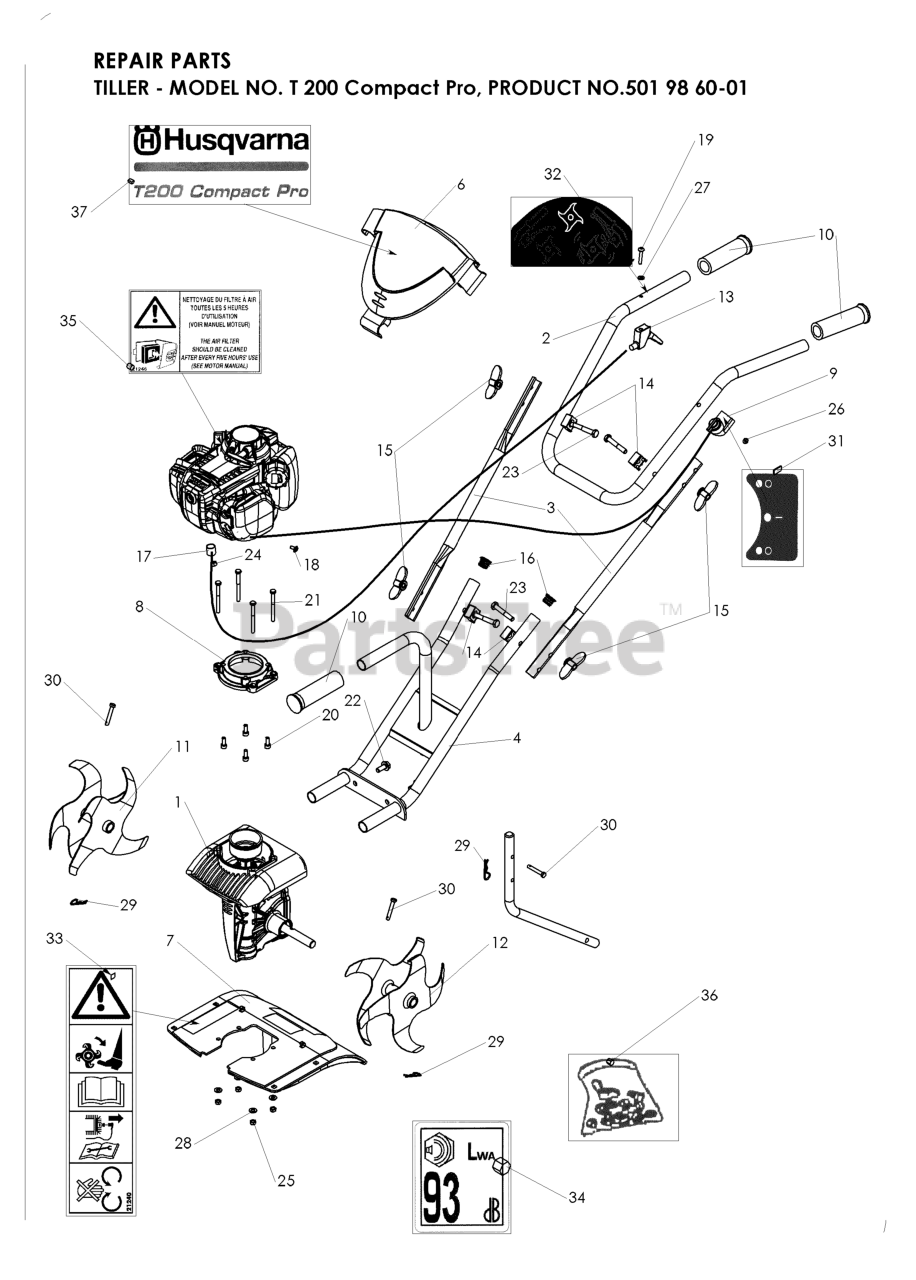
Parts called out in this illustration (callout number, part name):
1	STEERING WHEEL
2	AXLE ASSY
3	SPINDLE.ASM.LH.15"TIRES
4	SPINDLE.ASM.RH.15"TIRES
5	THRUST WASHER
9	BRNG T
10	DRAGLINK.15".TIRES
11	WASHER, LOCK 3/8
13	TUBE, PIVOT AXLE
15	NUT
17	SHAFT ASM STEERING
18	THRUST WASHER
19	STEERING SHAFT SUPPORT
22	SCREW.HX.WSH.HD
23	SHAFT ASSY PITTMAN
25	BRACKET STEERING
26	BUSHING.DRAGLINK (2 2)
27	GEAR.SECTOR
28	WASHER
29	SCREW 3/8-16X3/4
30	COTTER PIN
32	TIE ROD
36	BUSHING, STEERING
37	SCREW.TT.#10-32X.5.3/8.FLANGE
38	CAP.WHEEL.STEERING.GREY
39	Washer 13/32 x 1-1/20 x 11 Gauge
40	GRIPCO NUT
41	STEERING WHEEL ADAPTOR
42	BOOT STEERING
44	EXT SHAFT STEERING
46	CAP.SPINDLE.BLACK
47	ZERK M
51	NUT.71038.31-18.HEX.NYLOCK
54	BOLT.5/16-18X1-1/4 FULL.THREAD
62	STEERING KIT
65	SPACER BRACE AXLE
66	BEARING ARM
67	BOLT CARRIAGE
68	BRACE.AXLE.15"TIRES
79	WASHER
80	BOLT.HX.NYLON3/8-16X
82	BRACKET
85	FASTENER.XMAS.TREE
